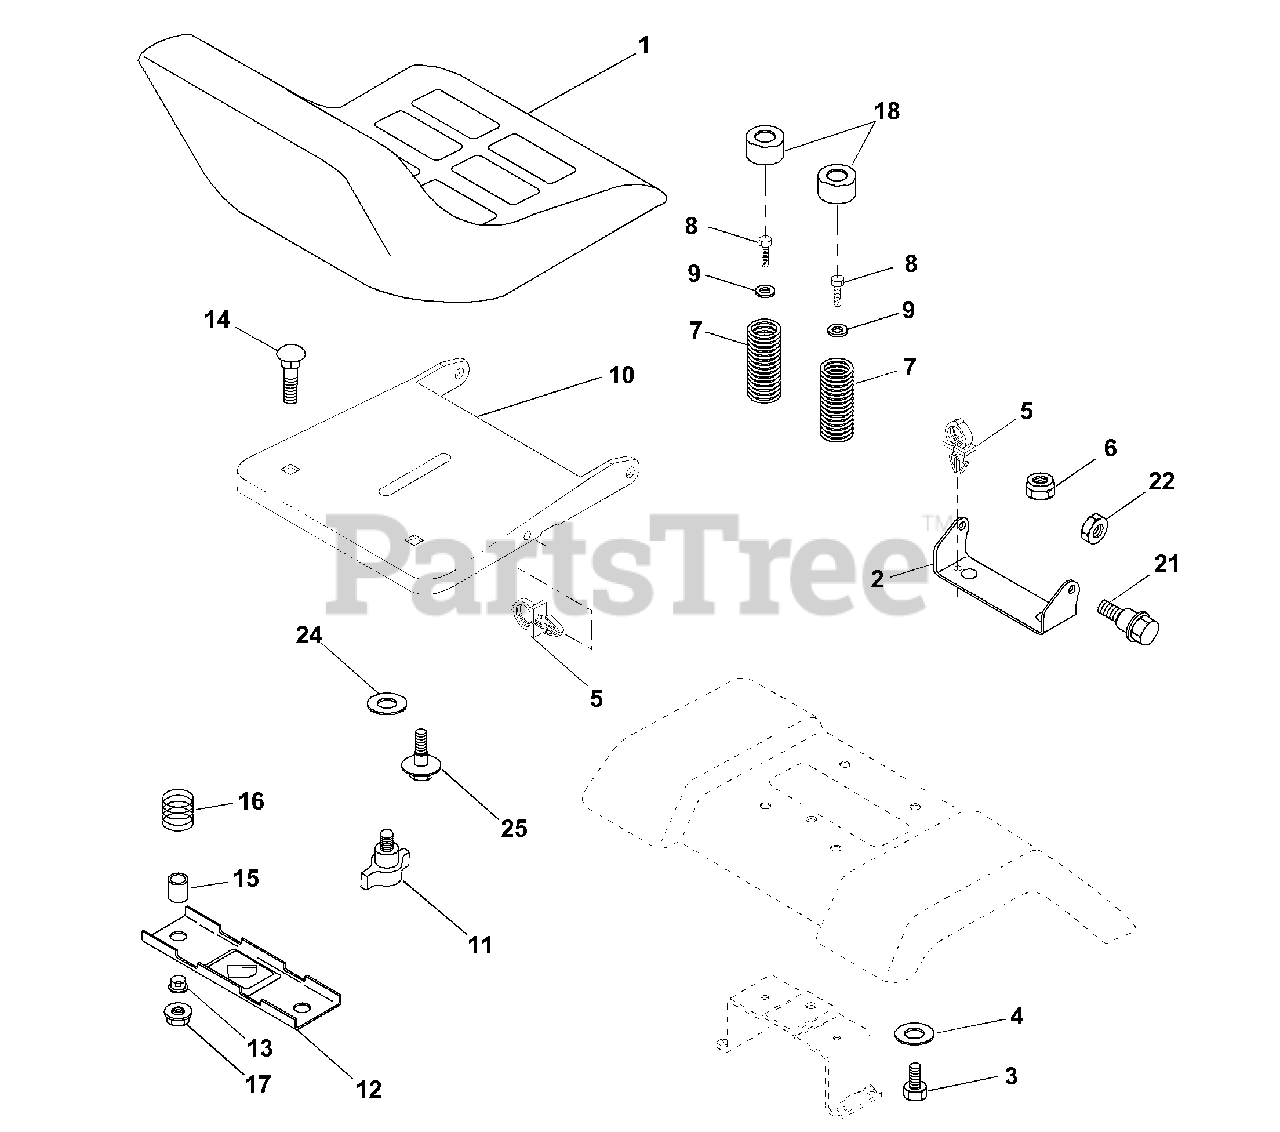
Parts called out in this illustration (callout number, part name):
1	Seat
2	Bracket Pivot Seat 8 720
3	Bolt Fin Hex 3/8-16unc X 1
4	Washer 13/32 X 1 X 10 Ga
5	Clip Push-In
6	Nut Hex w/Ins. 3/8-16 Unc
7	Spring Seat Cprsn 2 250 Blk Zi
8	Screw Thdrol 3/8-16 X 1-1/2
9	Washer 13/32 X 1 X 14 Ga.
10	Pan Seat
11	Knob Seat Adj Wingnut
12	Bracket Mounting Switch
13	Bushing Snap Blk Nyl 50 Id
14	Bolt Rdhd Sqnk 1/4-20x1-1/2
15	Spacer Split 28 x .88 Zinc
16	Spring Cprsn Plate
17	Nut Lock 1/4 Lge Flg Gr 5 Zinc
18	Cap Spring Seat
21	Bolt Shoulder 5/16-18 Unc
22	Nut Hex Lock W/Ins 5/16-18
24	Washer 17/32 X 1 X 12 Ga.
25	Bolt Shoulder 5/16-18 X 62
